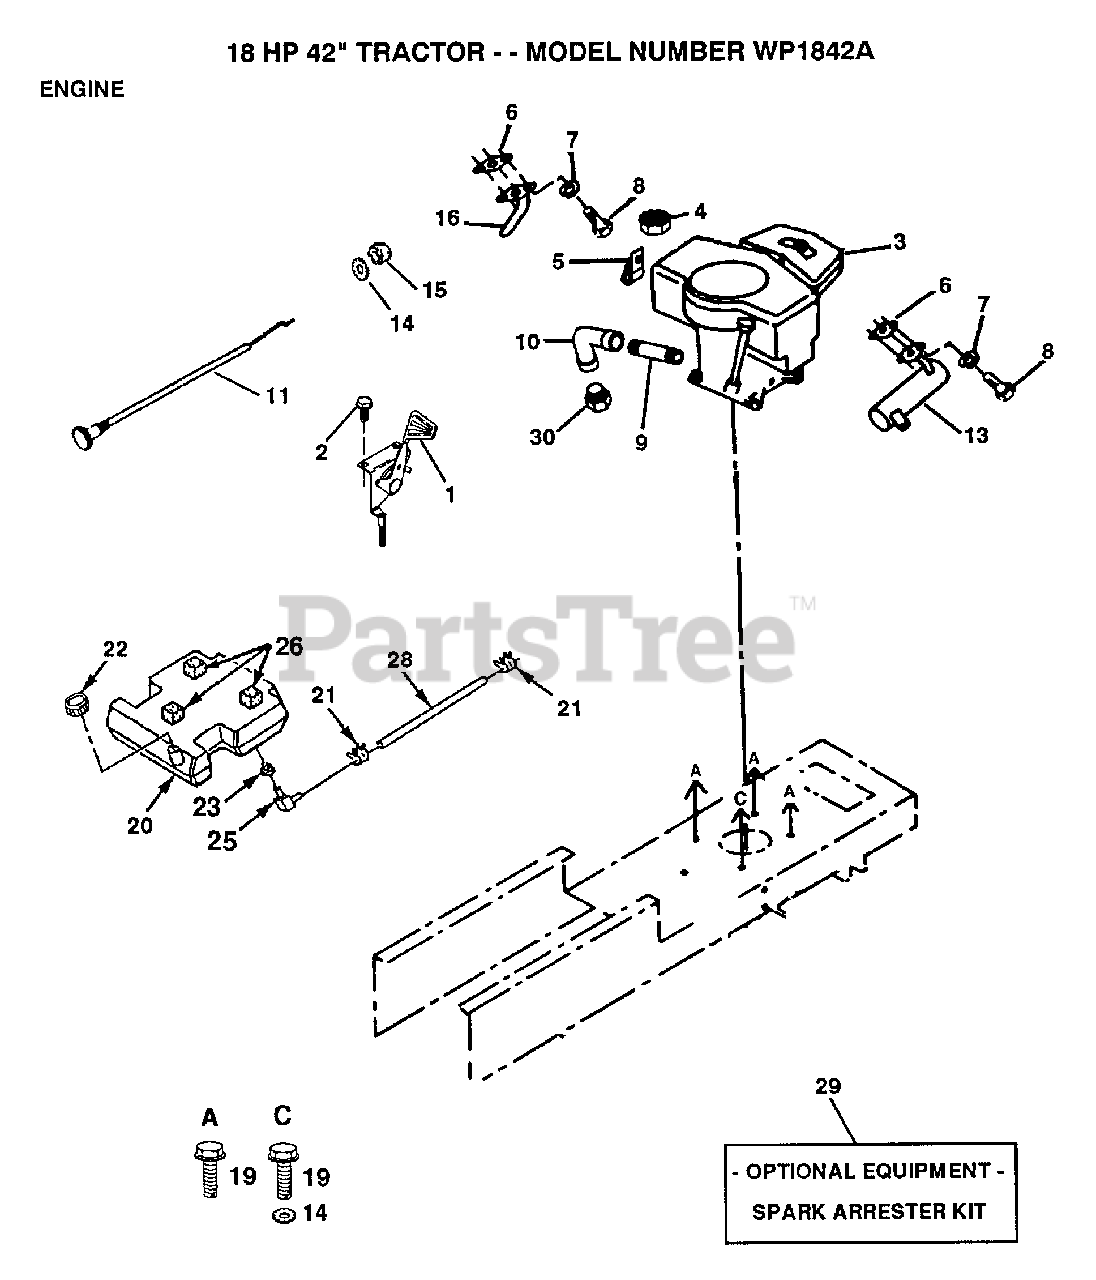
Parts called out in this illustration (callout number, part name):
2	SCREW LT
4	NUT
5	CLIP T
7	LOCKWASHER
9	PIPE NIPPLE LT
10	ELBOW
11	CHOKE CONTROL
14	LOCKWASHER
16	EXHAUST TUBE T
19	SCREW
21	HOSE CLAMP
23	BUSHING OUTLET T
25	FUEL TANK STEM GT
26	PAD-SPACER LT
